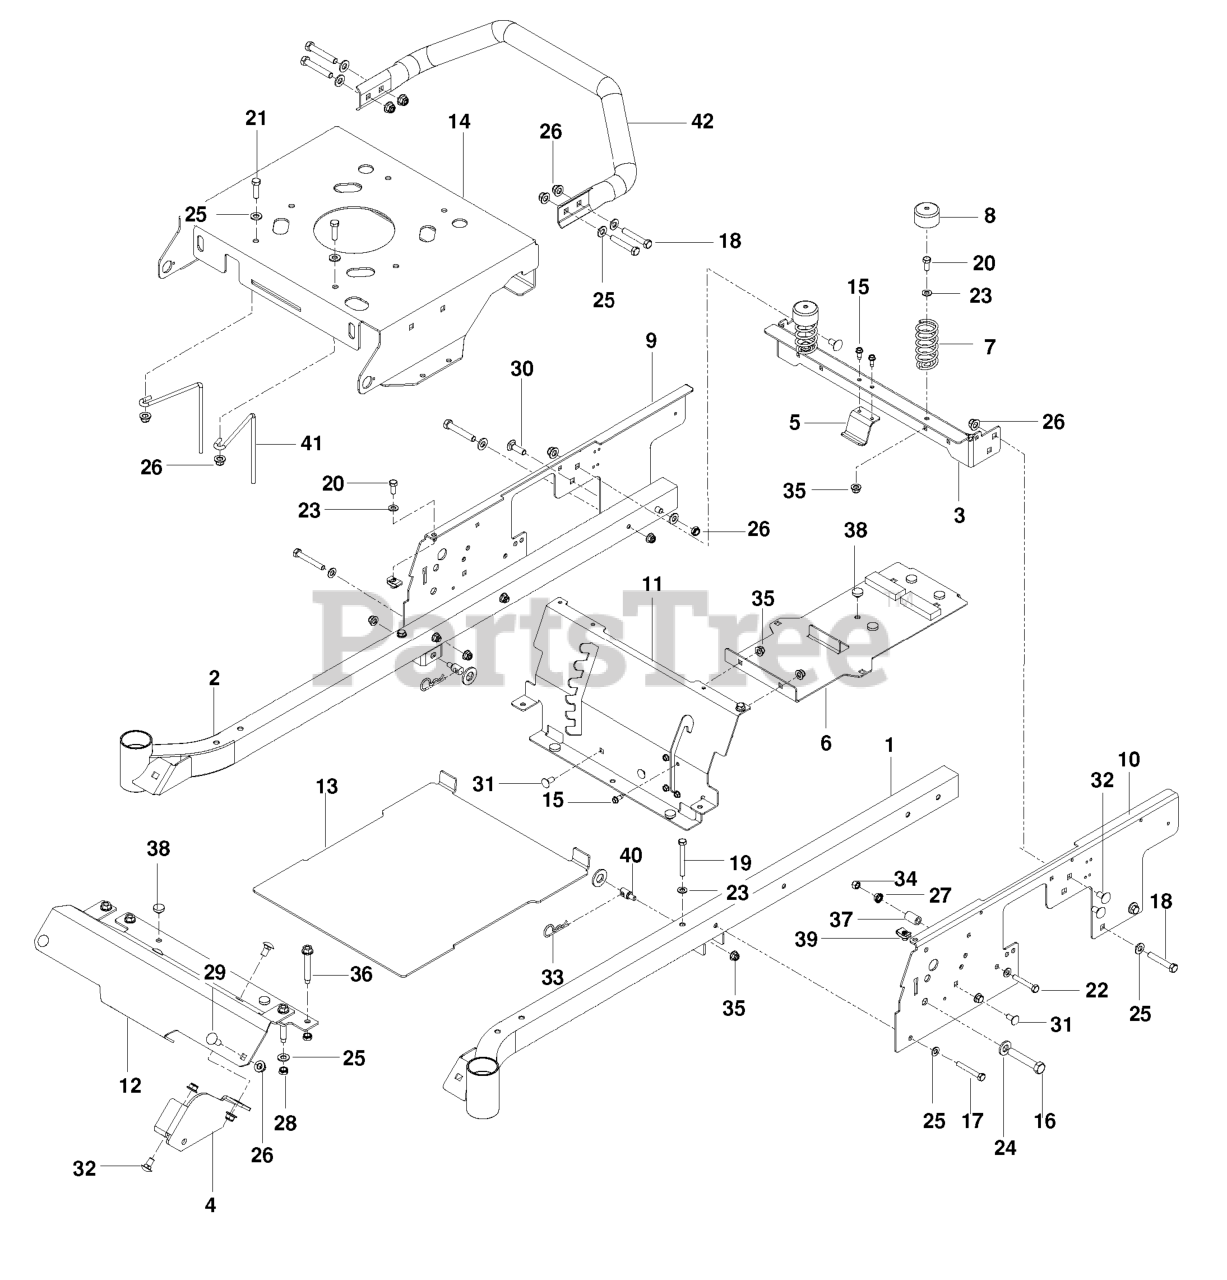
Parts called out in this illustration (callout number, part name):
1	FRAME TUBE, LH, ORG
2	FRAME TUBE, RH, ORG
3	SUPPORT, REAR SEAT, ORG
4	BRACKET, FRONT DECK, BLK
5	HOLDING DEVICE, FUEL TANK, BLK
6	SUPPORT, TANK/BATT, BLK
7	SEAT SPRING
8	SPRING CAP
9	PLATE.LH.SIDE.ORANGE
10	PLATE.RH.SIDE.ORANGE
11	PANEL, SEAT SUPP. ORG
12	FOOT.REST.30/38.ORANGE
13	FOOT PLATE, NARROW, ORG
14	PLATE, ENGINE, ORG
15	SCREW 1/4 X 5/8
16	HCS 1/2C X 2 3/4
18	HCS 3/8C X 2 1/4
19	HCS 5/16C X 2-3/4
20	HCS 5/16C X 3/4
21	HCS 3/8C X 1 1/4 GR5
22	HCS 5/16-18X2
23	FLAT WASHER 5/16 SAE
24	WASHER 1/2" FLAT
25	WASHER 3/8 SAE FLAT
26	NUT 3/8-16 HEX FLG NYLOC ZD
27	NUT 5/16C WHIZ
28	NUT HEX 3/8-16 NYLON, THIN
29	RHSNB 3/8C X 1
30	RHSNB 3/8-16 X 1-1/4
31	BOLT 5/16C X 3/4" CARRIAGE
32	RHSNB 3/8-16 X 3/4 GR5 ZD
33	HAIRPIN #4
34	NUT 5/16 NYLOC
35	5/16-18 NYLOC FLANGE NUT
36	ENGINE BOLT, SPECIAL
38	GROMMET, BUMPER
39	U-CLIP 5/16-18 NUT RETAINER
40	STUD.FASTNER.W/ANTI-ROTATE
41	BELT GUIDE
42	IMPACT BAR, ORG
